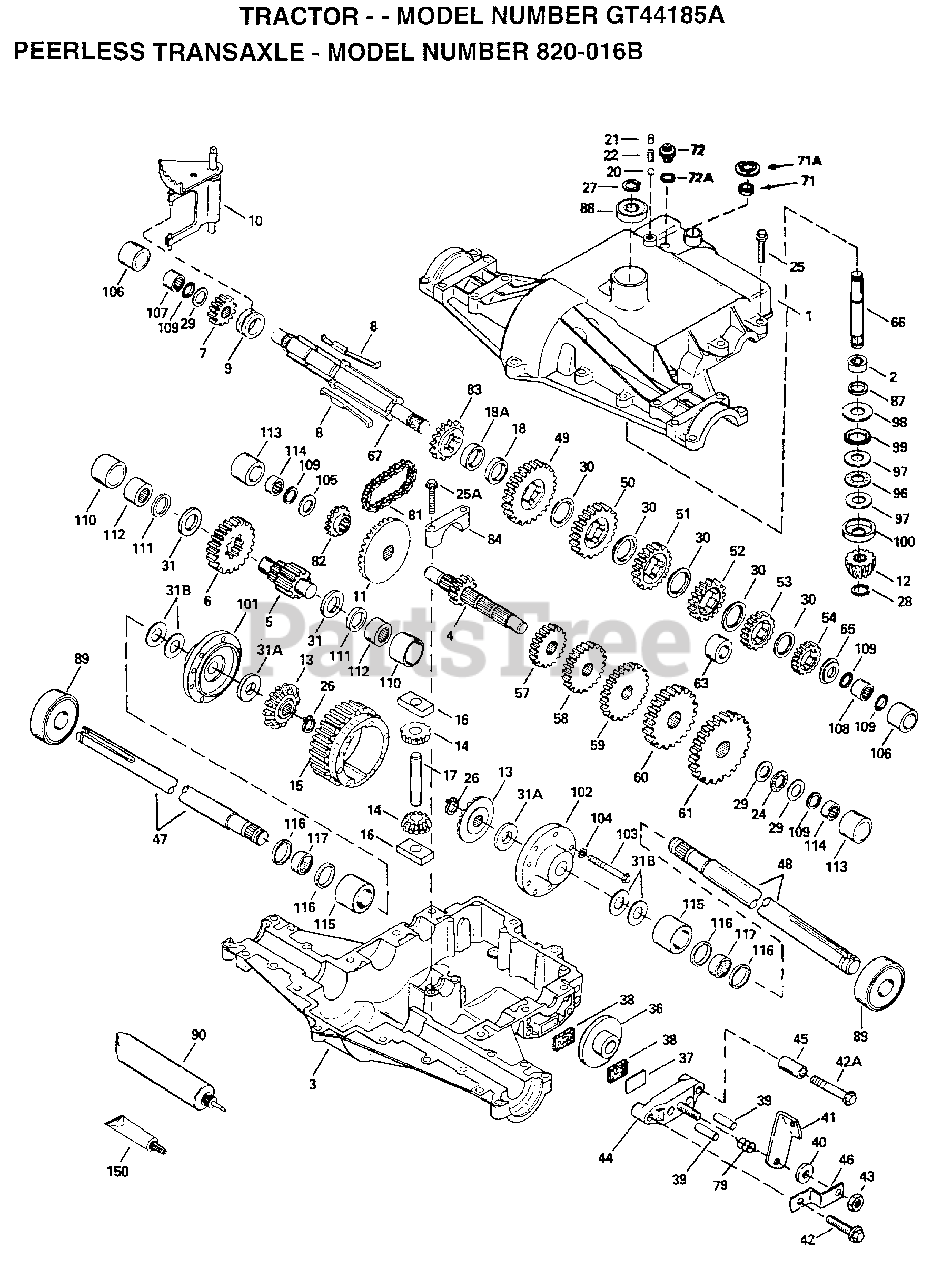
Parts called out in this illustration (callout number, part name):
1	COVER TRANSAXLE
2	BEARING NEEDLE
3	CASE TRANSAXLE
4	SHAFT COUNTER
5	SHAFT, OUTPUT, 9T
6	GEAR, OUTPUT, 35T
7	GEAR, SPUR, 15T
9	COLLAR SHIFT
10	ROD AND FORK ASSY SHIFT
11	GEAR BEVEL, 33T
12	BEVEL PINION, 13T
14	PINION, 10T
15	GEAR, RING, 31T
16	BLOCK DRIVE
18	SPACER, .350/.340 THICK
18A	SPACER, .276/.268 THICK
20	BALL STEEL, 5/16" DIA.
21	SCREW, 3/8-16 X 3/8"
24	THRUST BEARING
25	SCREW HEX HD 5/16-18 X 1-1/4
25A	SCREW, 1/4-20 X 1-1/4
28	RETAINING RING
29	WASHER THRUST
30	WASHER THRUST
31	WASHER THRUST
31B	WASHER THRUST
37	PLATE BRAKE PAD
41	LEVER BRAKE
42	SCREW, 1/4-20 X 1-1/4
42A	SCREW, 1/4-20 X 2-1/4
43	LOCKNUT 5/16-24
44	HOLDER BRAKE PAD
46	BRKT BRAKE LEVER
47	AXLE, 12-5/16" LONG
48	AXLE, 16-3/16" LONG
49	GEAR, SPUR, 41T
50	GEAR, SPUR, 35T
51	GEAR, SPUR, 30T
52	GEAR, SPUR, 25T
53	GEAR, SPUR, 22T
54	GEAR, SPUR, 19T
57	GEAR, SPUR, 15T
58	GEAR, SPUR, 20T
59	GEAR, SPUR, 25T
60	GEAR, SPUR, 28T
61	GEAR, SPUR, 31T
66	SHAFT INPUT
67	SHAFT BRAKE
71	SEAL SQUARE CUT
72	THREADED PLUG 9/16-18
81	CHAIN, ROLLER
82	SPROCKET 9T
83	SPROCKET 18T (REV)
84	BEARING CAP
87	OIL SEAL 3/4
88	BEARING BALL
89	BEARING BALL
90	GREASE BENTONITE, 32 OZ.
96	BEARING THRUST
97	WASHER THRUST
100	WASHER CUPPED
101	CARRIER DIFF THREADED HOLES
102	CARRIER DIFF
103	SCREW, 1/4-20 X 2-1/4
104	WASHER LOCK 1/4
107	BEARING NEEDLE
108	BEARING NEEDLE
110	SLEEVE STEPPED
111	RING SQ CUT
112	BEARING NEEDLE CAPPED
113	SLEEVE STEPPED
114	BEARING NEEDLE CAPPED
115	SLEEVE STEPPED
116	RING SQ CUT
117	BEARING NEEDLE
150	GASKET ELIMINATOR
